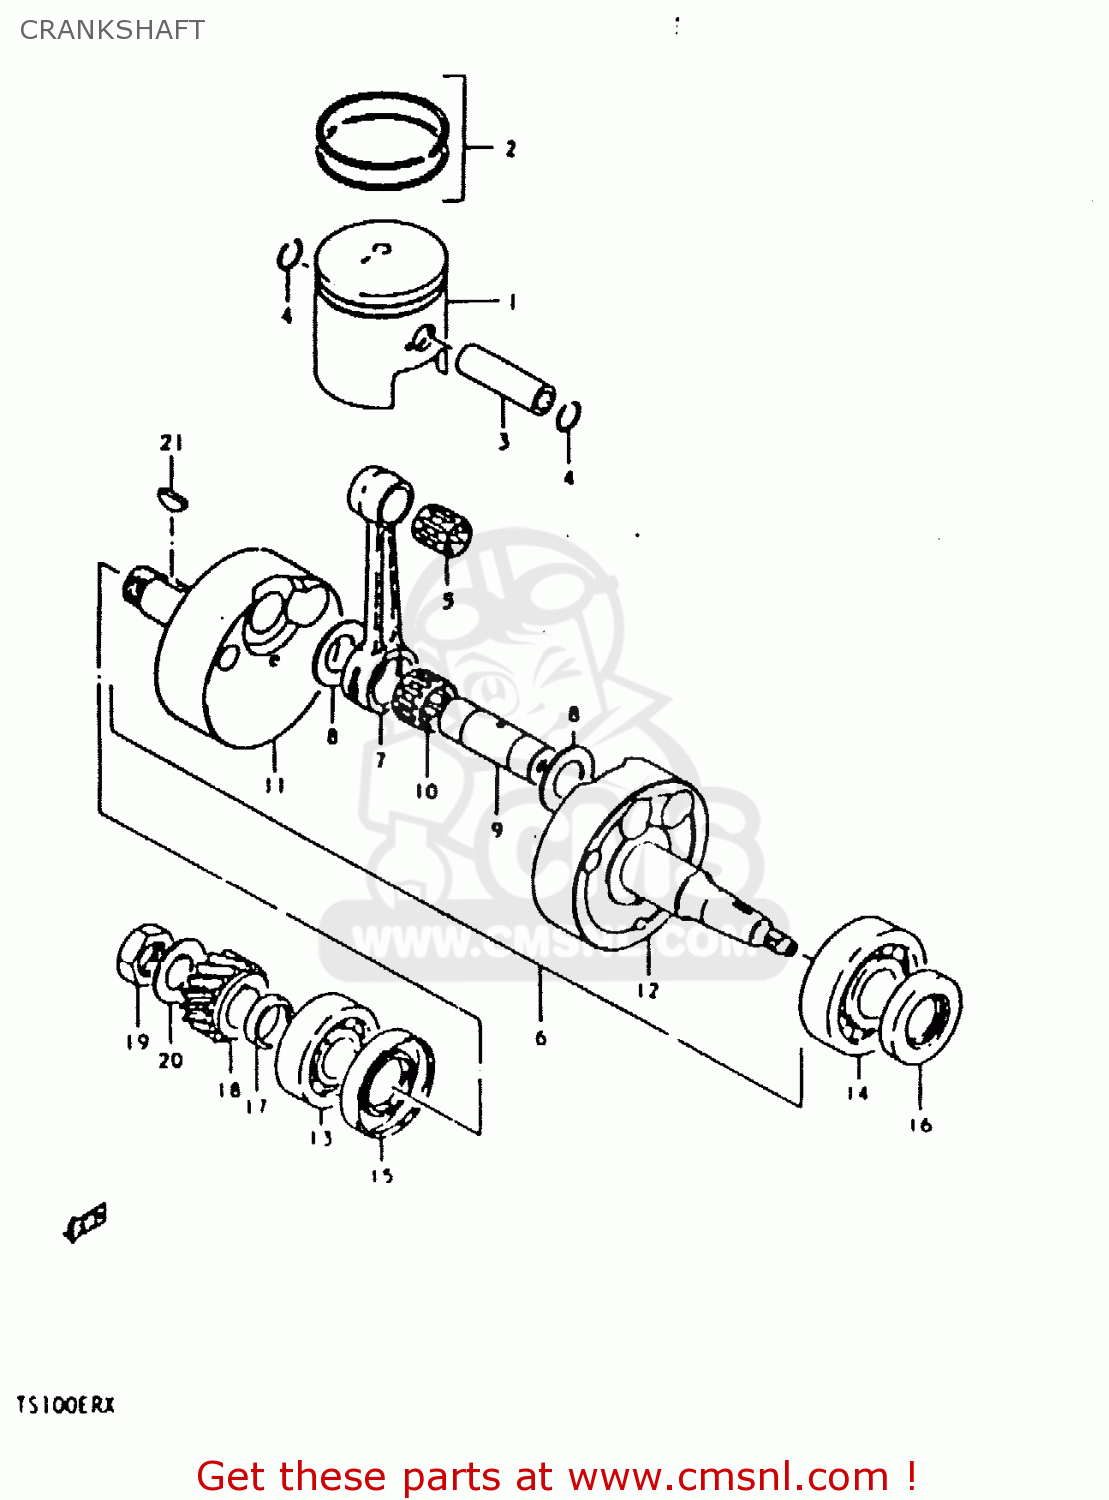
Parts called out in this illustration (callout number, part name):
1	PISTON
2	RING SET,PISTON
3	PIN,PISTON 14MM
4	RING,SNAP 14MM
5	BEARING
6	CRANKSHAFT ASSEMBLY
7	CONNECTING ROD
8	WASHER(19X32X1)
9	PIN,CRANK
10	BEARING(19X25X16)
11	CRANKSHAFT,R
12	CRANKSHAFT,LEFT
13	BEARING
14	BEARING(25X62X17)
15	SEAL,OIL(26X52X8)
16	SEAL,OIL(25X44X7)
17	SPACER(20X28X7)
18	GEAR,PRIMARY DRIVE
19	NUT
20	WASHER
21	KEY
